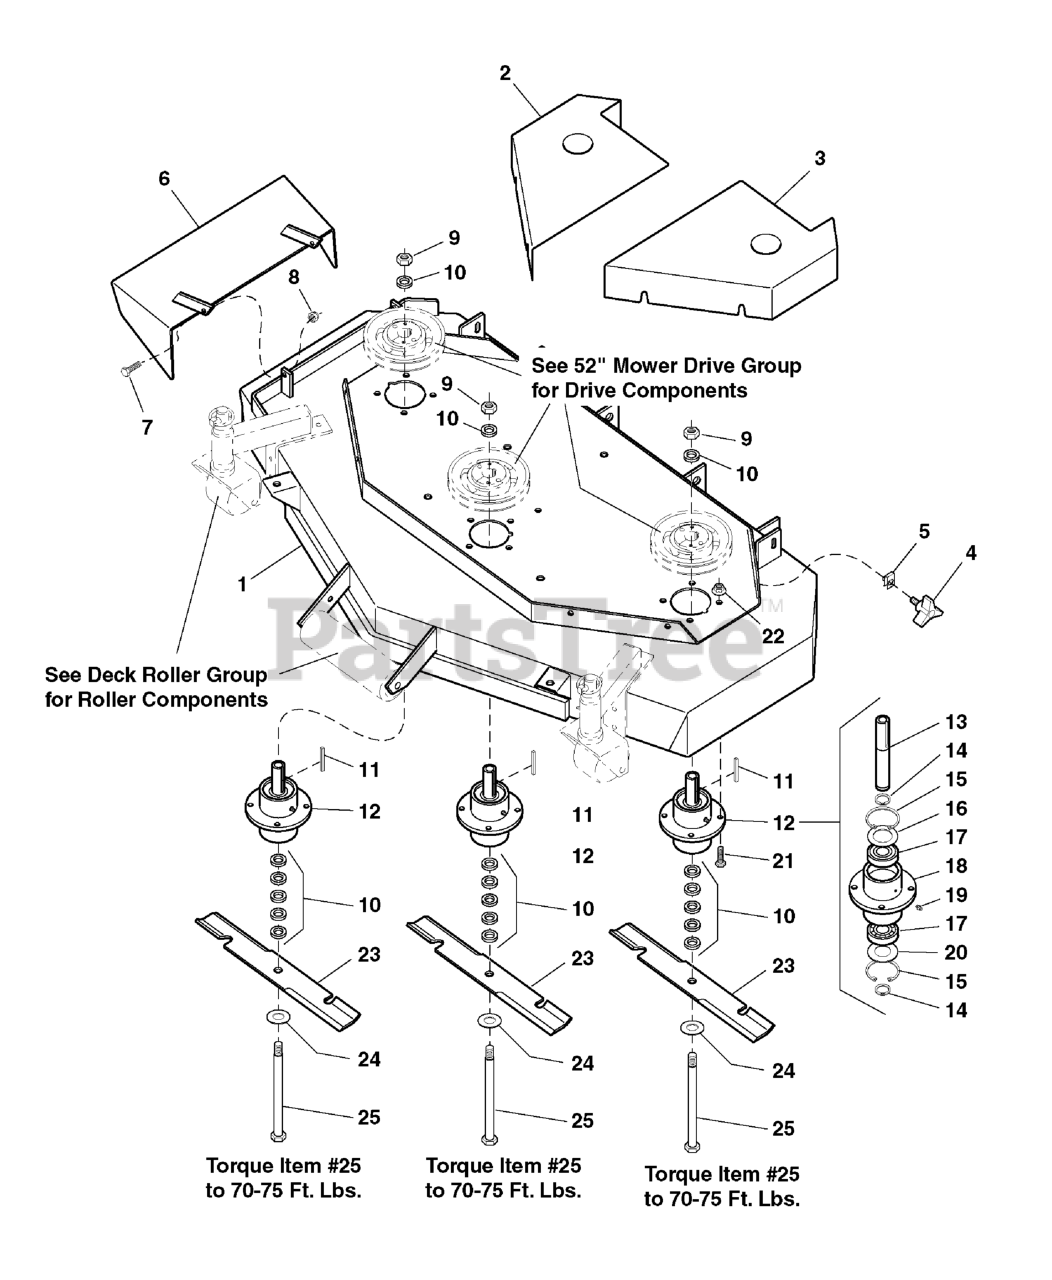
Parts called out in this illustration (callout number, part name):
1	DECK SHELL W/DECALS, 52, ISZ52
2	SPINDLE COVER-LH
3	SPINDLE COVER-RH
4	KNOB
5	BODY CLIP, 5/16-18-7GA MATERIAL
6	CHUTE, DISCHARGE WELDMENT
7	BOLT, 5/16-18 X 1 GD5 YZ
8	NUT, 5/16-18 Hex Nylon Lock
9	NUT, 5/8-11 Hex
10	SPACER, .63 x 1.06 x .23
11	KEY, 1/4 SQ. X 2-1/2
12	SPINDLE ASSEMBLY, Complete
13	SPINDLE SHAFT
14	SNAP RING, External
15	SNAP RING, Internal
16	SPINDLE WASHER, Top
17	BEARING
18	SPINDLE HOUSING
19	GREASE FITTING
20	SPINDLE WASHER, Bottom
21	BOLT, 5/16-18 x 1-1/4
22	NUT, 5/16-18 HEX SERRATED FLANGE (LARGE)
23	MOWER BLADE, 18"
24	WASHER, 5/8" USS
25	BOLT, 5/8-11 x 9-1/2
